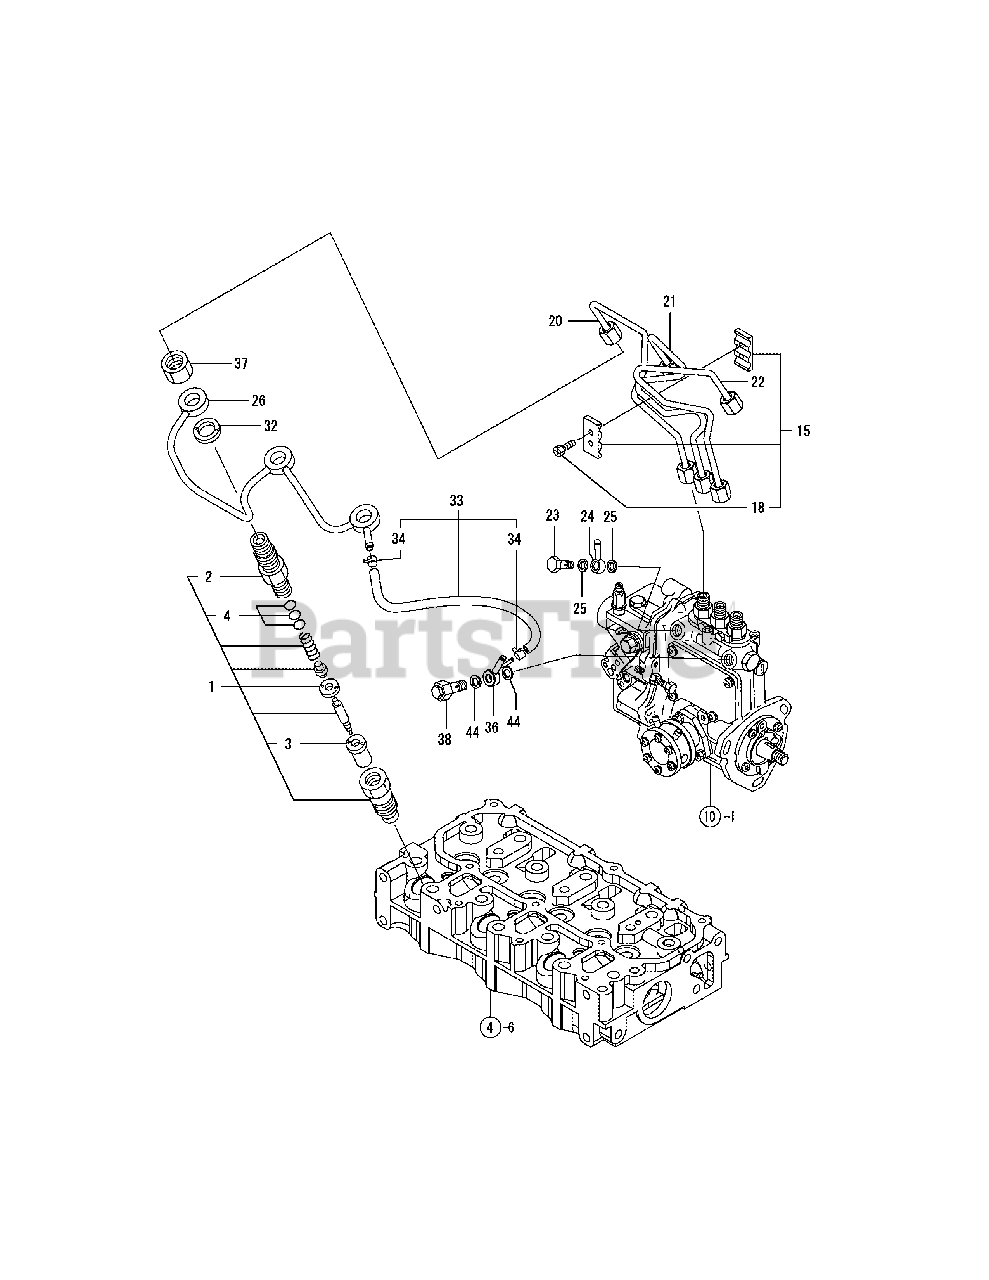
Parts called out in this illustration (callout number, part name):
1	Valve Assembly, Injection
2	Holder, Nozzle
3	Nozzle Assembly
15	Retainer, Inj. Pipe
18	Bolt, M 4 x 14, Hex Sckt.
20	Pipe, Fuel Injection
21	Pipe, Fuel Injection
22	Pipe, Fuel Injection
23	Bolt, Pipe Joint
24	Joint 12, Pipe
25	Seal Washer 12
26	Pipe Assembly, Return
32	Gasket, Return
33	Pipe, Fuel Return
38	Valve Assembly, Check
